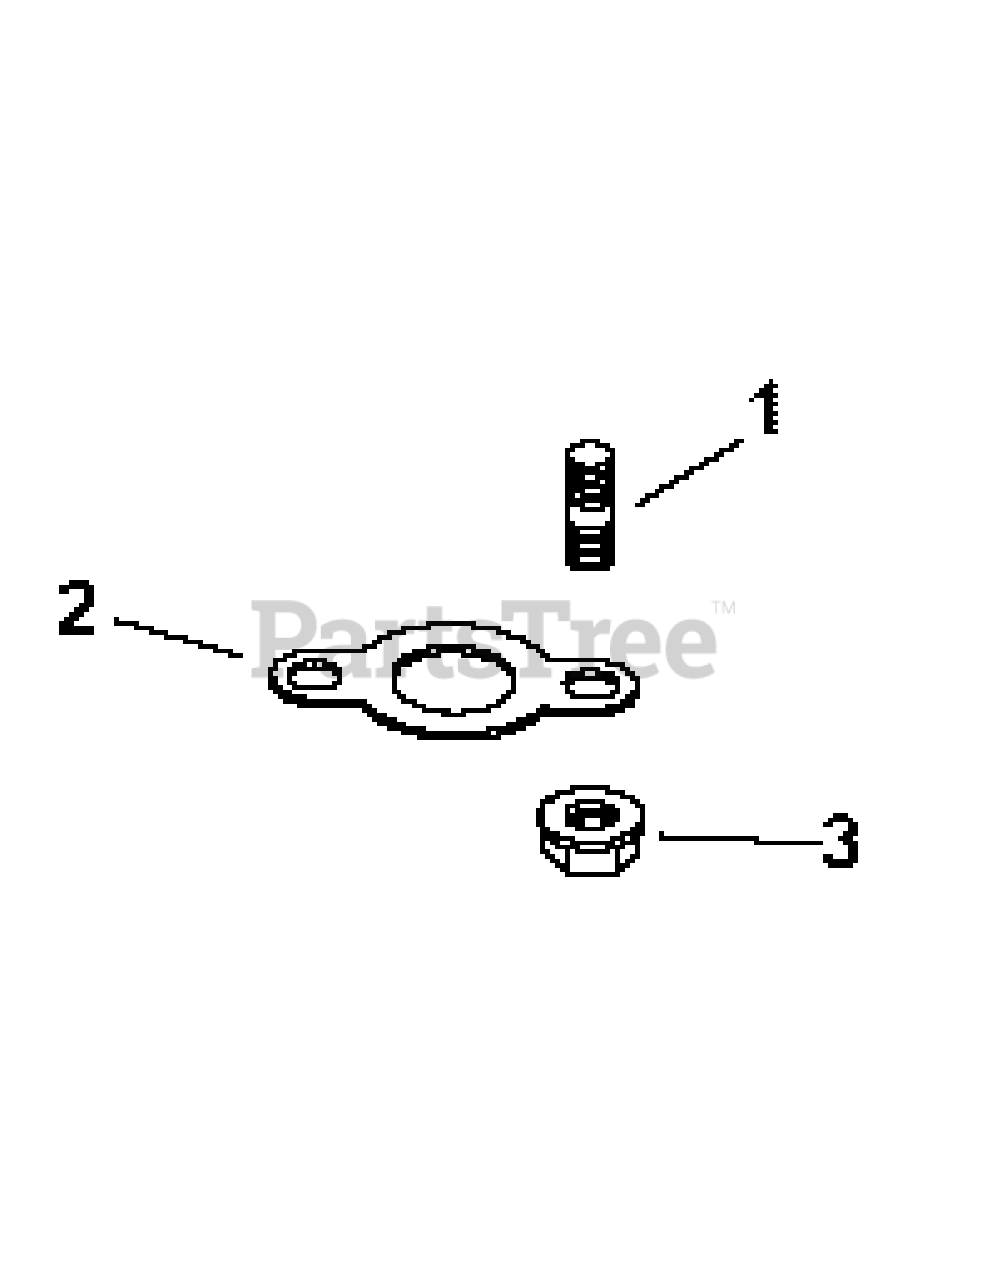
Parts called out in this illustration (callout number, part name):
1	Exhaust Stud
2	Exhaust Gasket
3	Hex Flange Nut
